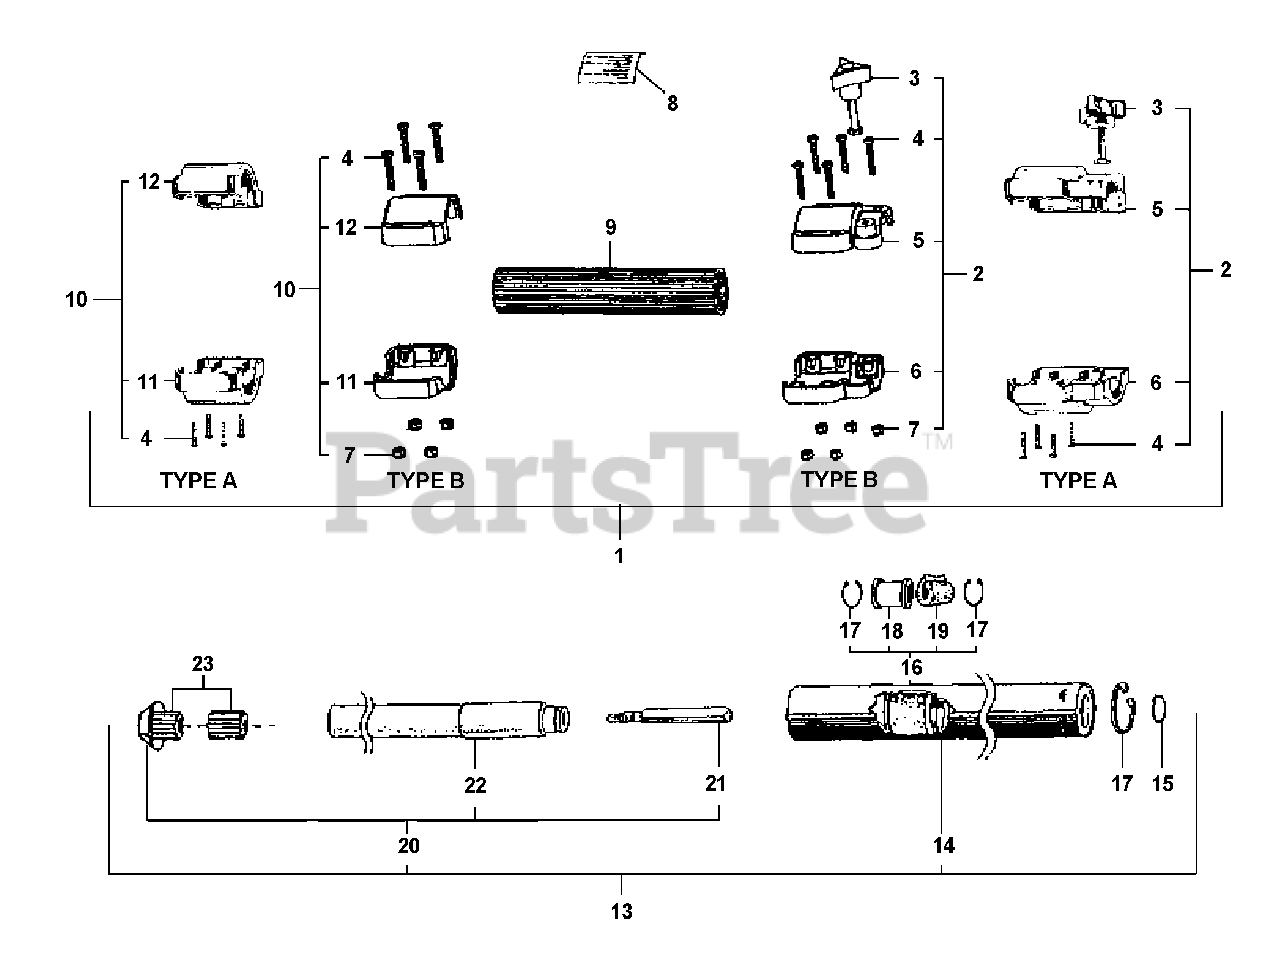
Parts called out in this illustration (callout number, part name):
1	MAIN PIPE ASSY - BLACK
2	COLLAR ASSY
3	THUMBSCREW
4	SCREW - 10-24 X 1-1/4"
5	COLLAR, MAIN PIPE - UPPER
6	COLLAR, MAIN PIPE - LOWER
7	LOCKNUT - 10-24
8	LABEL - CAUTION
9	PIPE, MAIN - YELLOW
10	FRONT CLAMP ASSY
11	COLLAR, MAIN PIPE - LOWER
12	COLLAR, MAIN PIPE - UPPER
13	MAIN PIPE ASSY - YELLOW
14	MAIN PIPE ASSY - YELLOW
15	RING, RETAINING
16	DRIVESHAFT GUIDE ASSY
17	RING, RETAINING
18	GUIDE, DRIVESHAFT
19	PAD, FOAM
20	DRIVESHAFT ASSY - UPPER
21	CONNECTOR, SHAFT
22	DRIVESHAFT
23	ADAPTER, DRIVESHAFT - UPPER
